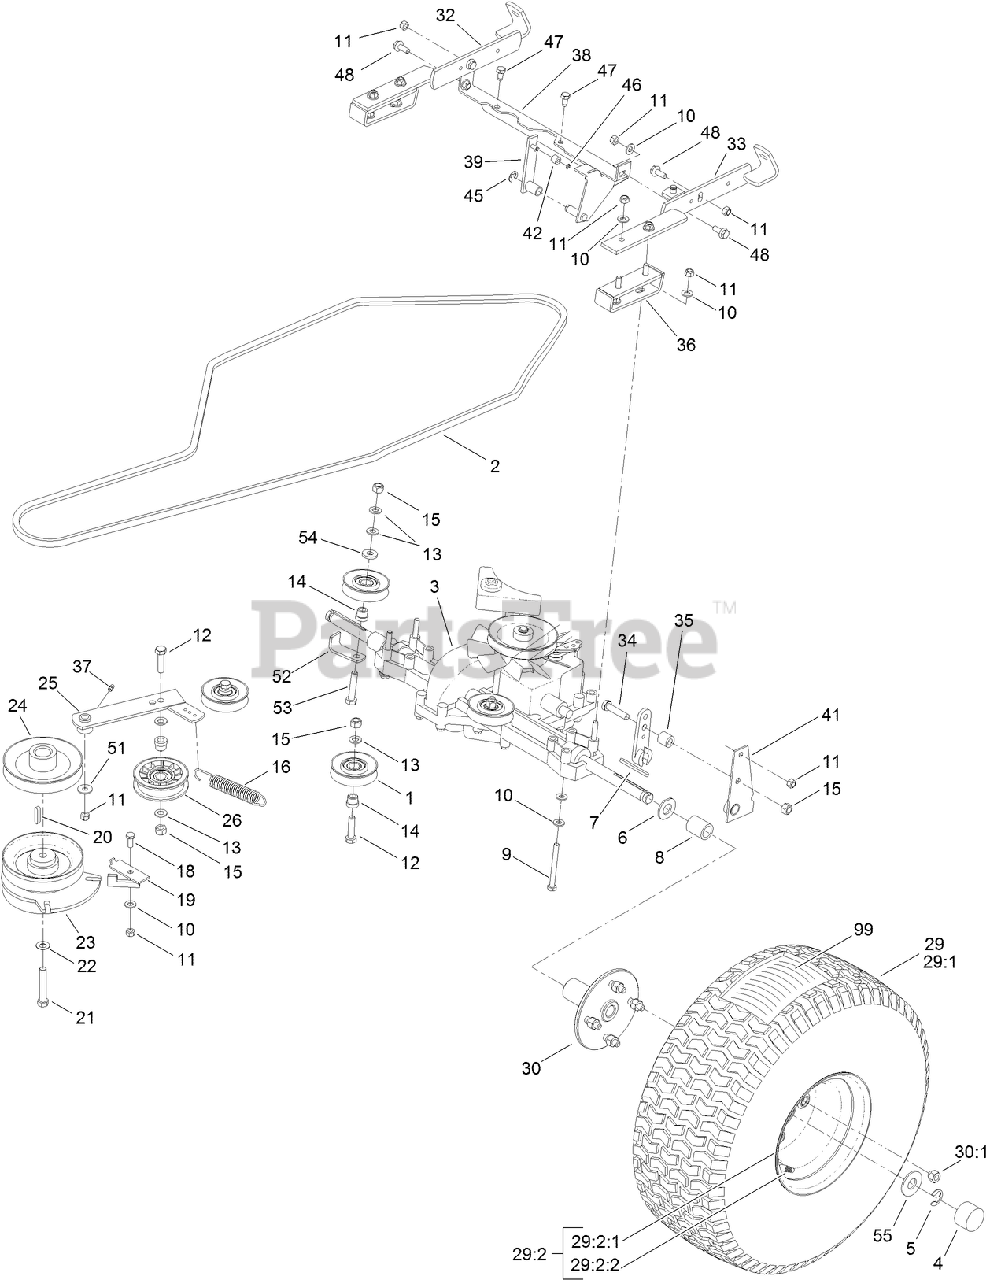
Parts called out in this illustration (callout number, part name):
1	PULLEY-IDLER
2	V-BELT-TRACTION
4	CAP-HUB
5	CLIP-SPRING
6	WASHER
7	KEY-SQUARE
8	SPACER-AXLE
9	SCREW-HH
10	WASHER-PLAIN
11	NUT-LOCK, NI
12	SCREW-HH
13	WASHER-FLAT
14	BUSHING-IDLER
15	NUT-LOCK, NI
16	SPRING
18	SCREW-HH
19	RETAINER
20	KEY-SQUARE
21	SCREW-HH
22	WASHER-SPRING, BELLEVILLE
23	CLUTCH-ELECTRIC
24	PULLEY-ENGINE
25	ARM-IDLER
26	PULLEY-IDLER
29	TIRE AND WHEEL ASM
29:2	WHEEL ASM
29:2:1	Loose Parts Package
29:2:2	Valve-Tire
30	HUB-WHEEL
30:1	NUT-LUG
32	Bracket-Right
33	Bracket-Left
34	SCREW-HH
35	SLEEVE
36	Plate-Reinforcing
37	FITTING-GREASE
38	Bar ASM
42	Roller
45	Stirrup
46	STIRRUP
47	SCREW-THREAD FORMING
48	SCREW-HEX
51	WASHER-PLAIN
52	RETAINER-BELT
53	SCREW-HH
54	WASHER-FLAT
55	WASHER
